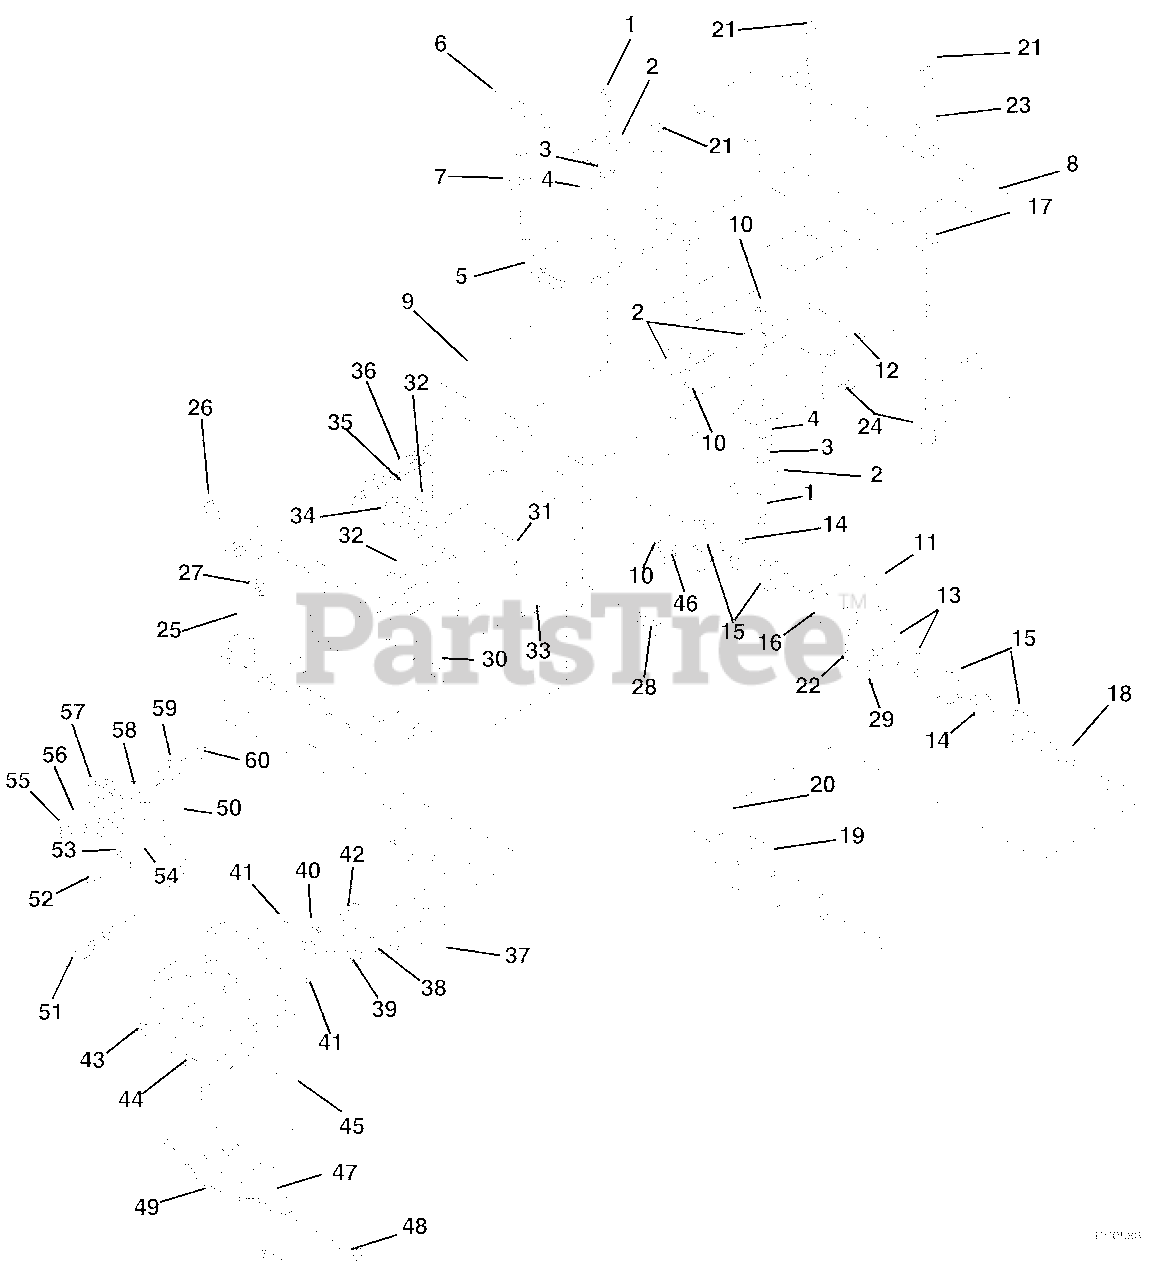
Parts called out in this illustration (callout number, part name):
1	@BLT-HEX .31-18X1.25 GR5 YWZC
2	RETAINER
3	@WSHR-LK-EXT.326X.599X.031YWZC
4	PIVOT CENTER
5	PLATE, TOP MOUNT
6	T-LOCK HANDLE
7	WASHER, CUPPED SERRATED, .375
8	GUARD, SHAFT
9	FRAME, ADAPTOR
10	@NUT-LK-CTR .31-18 YWZC
11	@BLT-RDHDSQNK .31-18X.75 G5YZ
12	PLATE, BOTTOM MOUNT
13	WSHR-FL-STL 1.015X1.500X.125
14	BRG-BALL .884HEXX52MMX1.07
15	BEARING FLANGE
16	SPACER 1.006X1.307X.500
17	WSHR-FL-STL .390X.88X.18 YWZC
19	JOINT, UNIVERSAL
20	PIN-ROLL .188X1.50
21	@BLT-HEX .38-16X3.25 GR5 YWZC
22	SPROCKET
23	@WSHR-FL-STL.406X.812X.065 YWZ
24	@NUT-LK-CTR .38-16 YWZC
25	PLATE, MOUNTING-BROOM
26	BLT-SERHFWH .38-16X.75 YWZC
27	NUT-RETNR .38-16 TINRMAN
28	@BLT-HEX .38-16X.75 GR5 YWZC
29	PIN-ROLL .188X1.75
30	@NUT-LK-CTR .38-16 YWZC
31	GEAR BOX ASSEMBLY
32	KEY-WDRF .188X.75X.313 SAE 9
33	@BLT-HEX .38-16X1.25 GR5 YWZC
34	SPROCKET
35	SCR-SET .25-20X.38 SKHCUPNL OH
36	CHAIN
37	PLATE, STIFFENER
38	@WSHR-LK .38X.094 REG YWZC
39	@NUT-HEX .38-16 YWZC
40	HUB ASSEMBLY
41	SCR-SET .31-18X.38 SKHCUPDL
42	BLT-SERRDHD SL .31-18X.75 YZ
43	@NUT-SPNLK-FLG .312-18 YWZC
44	PLY-V 9.0 X 1.25 3BLT
45	V-BELT, 4L-RAW EDGE
46	@WSHR-FL-STL.38X.875X.083 YWZC
47	BELT RETAINER
48	@BLT-HEX .25-20X.50 GR5 YWZC
49	@NUT-LK-CTR .25-20 YWZC
50	ARM, AUGER/BRAKE-HIGH W/LINING
51	SG-TENS .062X.56X8.0 WLD 11
52	@BLT-HEX .31-18X.75 GR5 YWZC
53	WSHR-LK .312X.097 HVY YWZC
54	WSHR-FL-STL .328X1.0X.094 YWZC
55	@NUT-LK-CTR .31-18 YWZC
56	@WSHR-FL-STL.344X.688X.065YWZC
57	IDLER
58	SPCR, BRG .315X.50X.688X.281
59	@WSHR-FL-STL.38X.875X.083 YWZC
60	@BLT-HEX .31-18X1.25 GR5 YWZC
